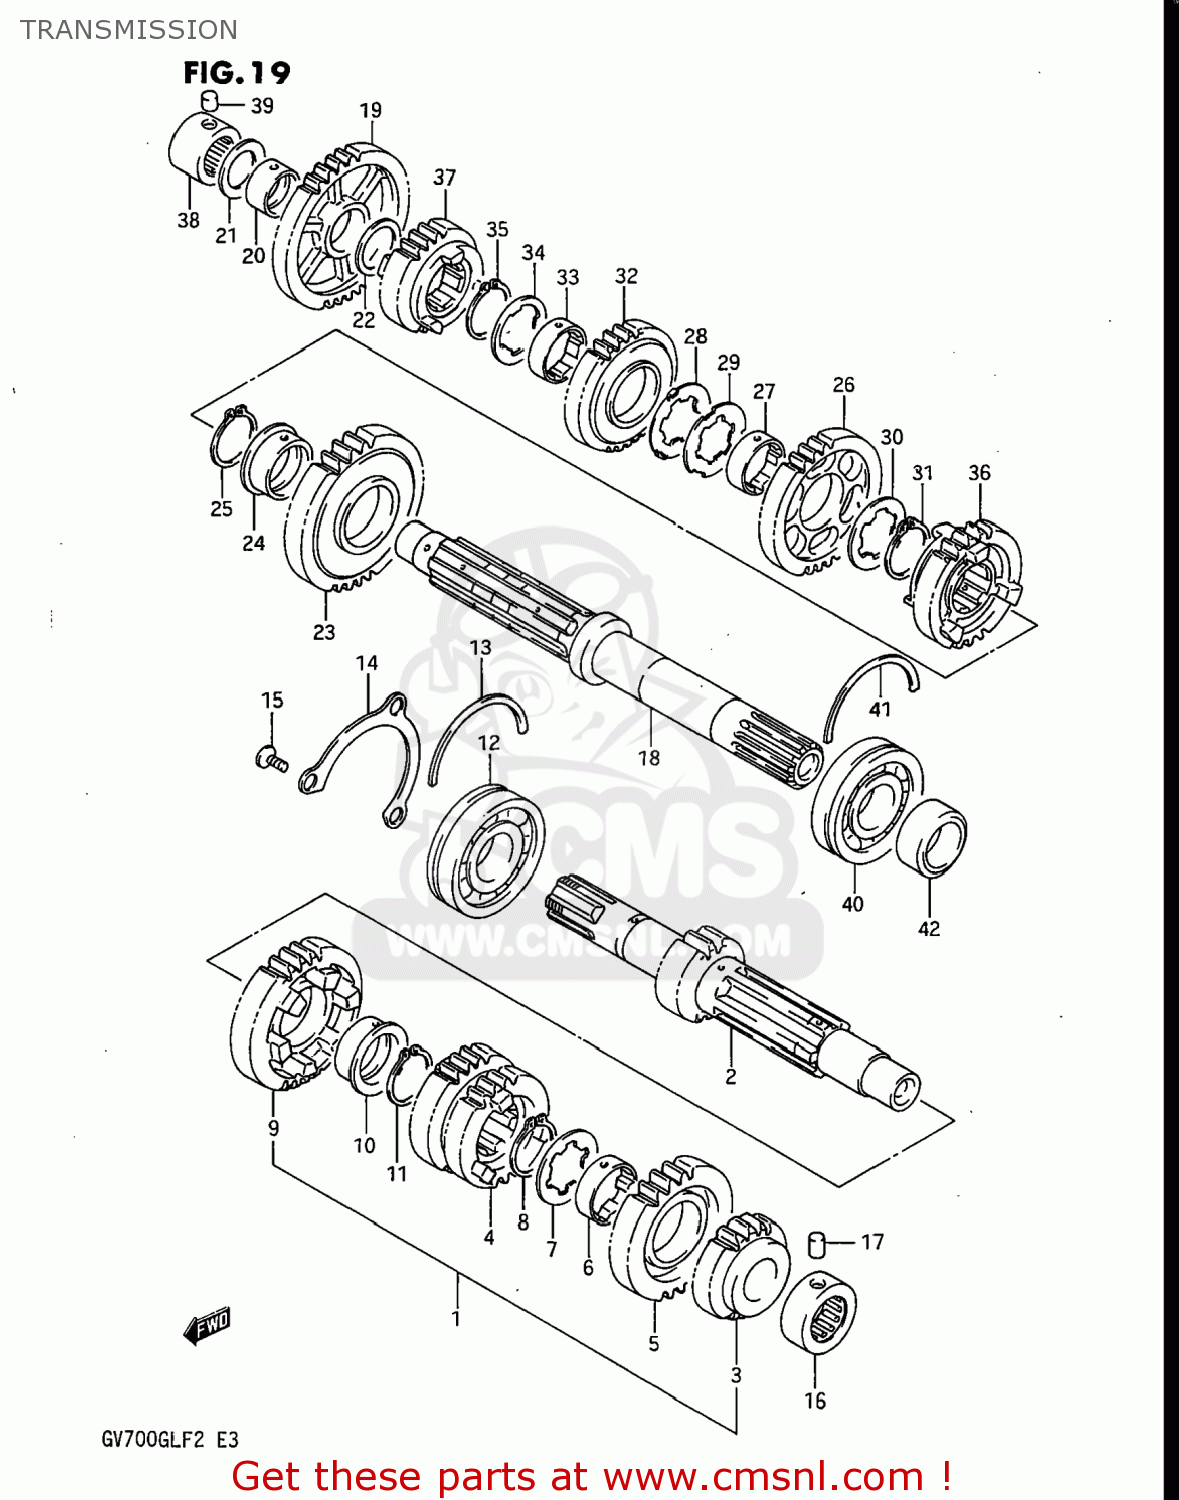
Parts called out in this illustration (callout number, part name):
1	SHAFT,COUNTER
2	SHAFT,COUNTER
3	GEAR,SECOND DRIVE
4	GEAR,THIRD DRIVE
5	GEAR,FIFTH DRIVE
6	BUSH
7	WASHER,LOCK
8	CIRCLIP
9	GEAR,SIXTH DRIVE
10	BUSH(28X32X2)
11	CIRCLIP
12	BEARING(25X62X17)
13	C-RING
14	PLATE,COUNTERSHAFT BEARING
15	SCREW
16	ROLLER BEARING (20X36X1
17	PIN
18	SHAFT,DRIVE
19	GEAR,FIRST DRIVEN
20	BUSHING
21	WASHER
22	WASHER
23	GEAR,SECOND DRIVEN
24	BUSH(28X32X2)
25	CIRCLIP
26	GEAR,THIRD DRIVEN
27	BUSH
28	WASHER
29	WASHER,LOCK
30	WASHER,LOCK
31	CIRCLIP
32	GEAR,FOURTH DRIVEN
33	BUSH
34	WASHER,LOCK
35	CIRCLIP
36	GEAR,FIFTH DRIVEN
37	GEAR,SIXTH DRIVEN
38	BEARING(20X34X20)
39	PIN
40	BALL BEARING 25X62X17
41	C-RING
42	SPACER,DRIVESHAFT,LEFT
